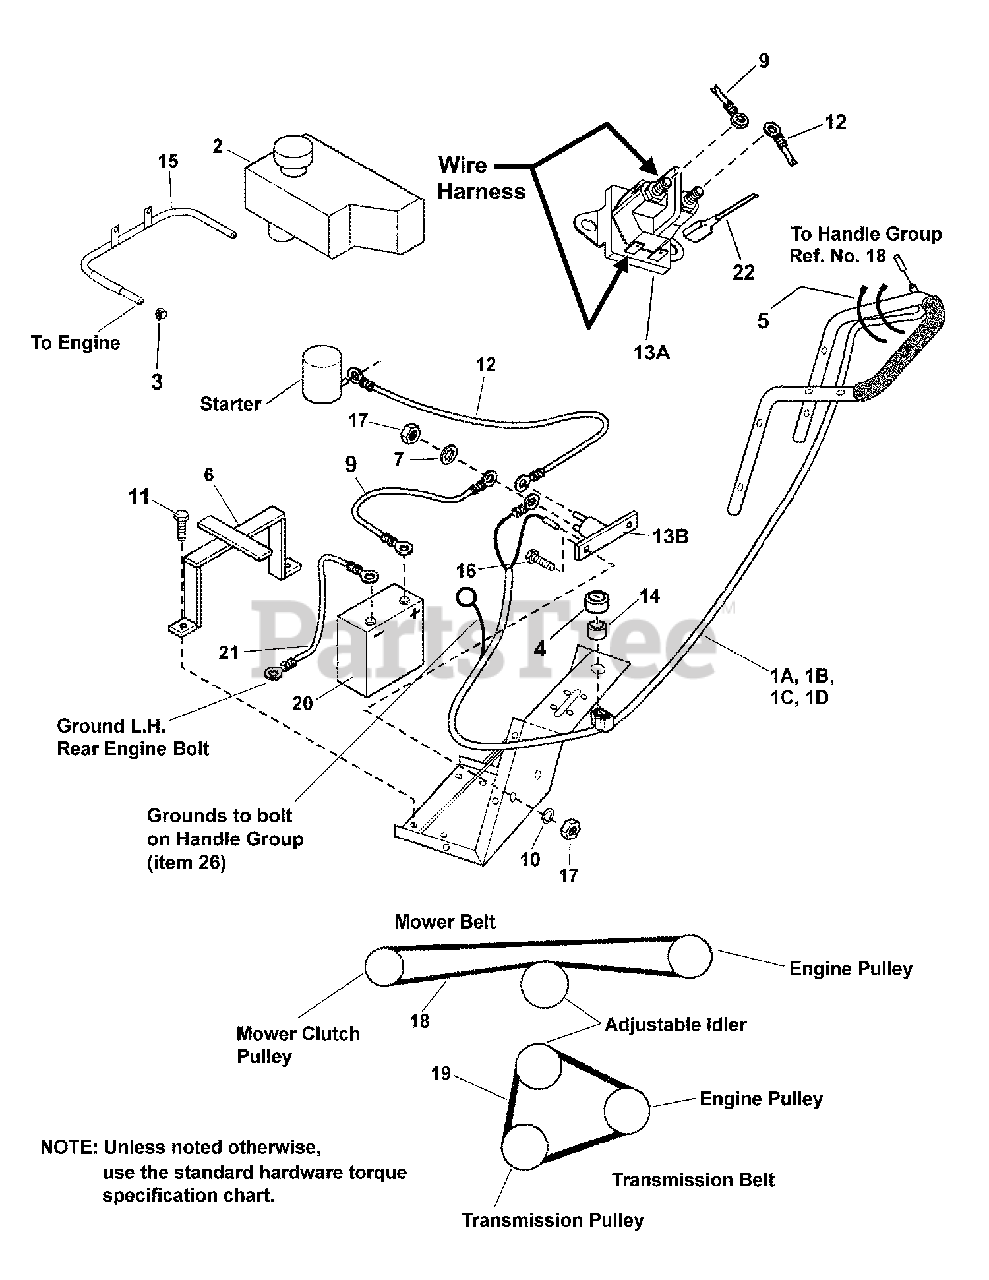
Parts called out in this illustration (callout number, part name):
1A	WIRE HARNESS, Briggs
1B	WIRE HARNESS, Briggs
1C	WIRE HARNESS, Kawasaki
1D	WIRE HARNESS, Kawasaki
2	FUEL TANK, Auxilliary
3	CLAMP, Fuel Hose
4	BEZEL
5	CABLE TIE, 7"
6	BRACKET, Battery Hold Down
7	WASHER, 1/4" Internal Lock
9	CABLE, Battery Positive to Solenoid
10	WASHER, 1/4" Split Lock
11	SCREW, Tek #12 x 3/4" Hex Head Cap
12	CABLE, Solenoid to Starter
13A	SOLENOID - Super Trombetta - 2 Terminal
13B	SOLENOID, Single Pole
14	SWITCH, Keyed Start
15	AUX FUEL LINE w/Clamps
16	SCREW, 1/4-20 x 3/4" Hex Head Cap, GR 5
17	NUT, 1/4-20 Hex, GR 5 or B
18	BELT, Blade Clutch
19	BELT, Transmission
20	BATTERY, 12V, 3 Amp, 190 Cold Cranking Amp (Incl. Drain Tube)
21	CABLE, Battery Negative to Ground
22	GROUND WIRE, 16 Ga., Green, 19" long
